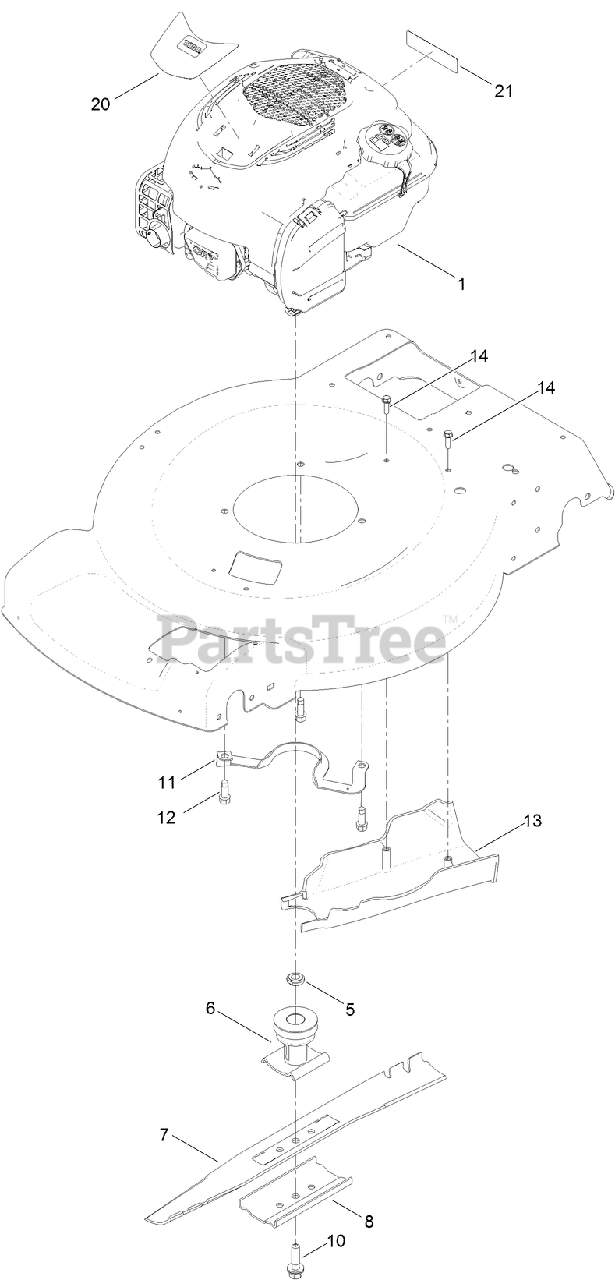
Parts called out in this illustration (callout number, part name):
5	SPACER-DRIVER
6	DRIVER-BLADE
7	BLADE-22 INCH
8	SUPPORT-BLADE
10	BOLT-BLADE
11	GUIDE-BELT
12	SCREW-TAPTITE
13	COVER-BELT, REAR
14	SCREW-HWH
20	DECAL-SHROUD, BRIGGS
21	DECAL-ARRESTER, SPARK
